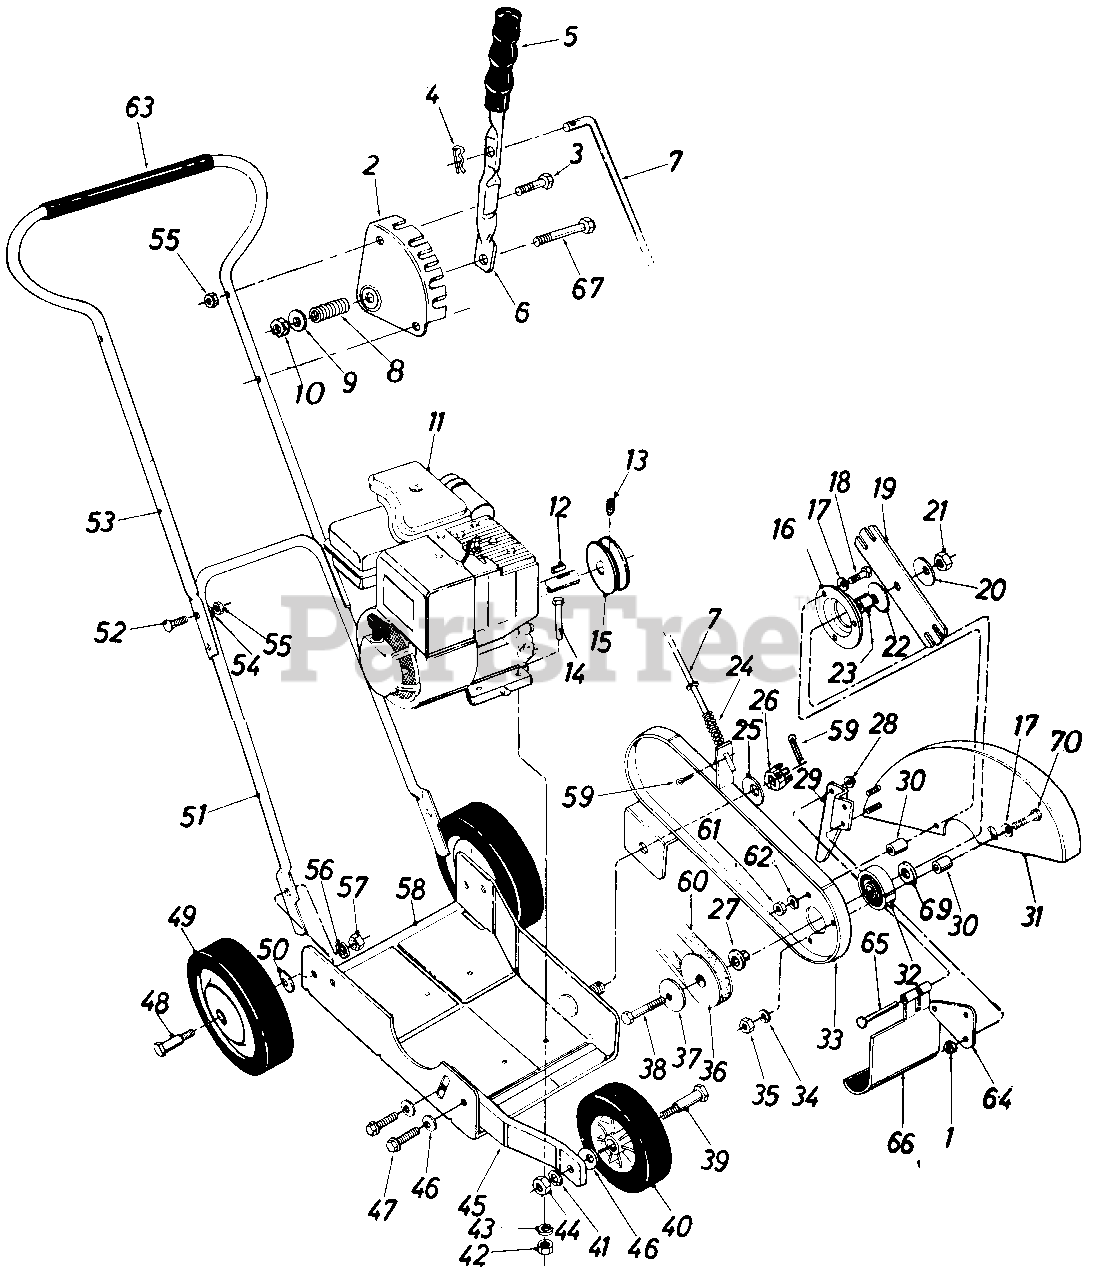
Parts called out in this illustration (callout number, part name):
1	Hex Cent. L.-Nut 1/4-20 Thd.
3	Hex Bolt 1/4-20 x 1.25" Lg.
4	Cotter Pin 1/8" Dia. x 1.0" Lg.
5	Grip
6	Clutch Handle
7	Clutch Rod
8	Compression Spring .50" O.D. x 1.38" Lg.
9	Fl.-Wash. .34" I.D. x .62" O.D x 063
10	Hex Cent. L.-Nut 5/16-18 Thd.
11	Engine
12	Sq. Key 3/16 x 1.0" Lg.*
13	Set Scr. 1/4-28 x 1/4" Lg.
14	Hex Bolt 5/16-18 x 1.50" Lg.*
15	Engine Pulley
16	Bearing Housing
17	Bell.-Wash. .34" I.D. x 88" O.D. x .060
18	Hex Bolt 5/16-18 x 1.25" Lg.*
20	Bell.-Wash. .535" I.D. x 1.50" O.D. x.052
21	Hex Cent. L.-Nut 1/2-20 Thd.
22	Bell.-Wash. .535" I.D. x 1.50" O.D. x .052
23	Spacer
24	Compression Spring .57" O.D. x 1.92" Lg.
25	Bell.-Wash. .535" I.D. x 1.50" O.D. x .052
26	Hex Castle Nut 1/2-20 Thd.
27	Shoulder Spacer
28	Push Cap
29	Guide
30	Spacer .354" I.D. x .635" O.D. x .510" Lg.
33	Spindle Bracket Ass'y.
34	L.-Wash. 5/16" I.D.*
35	Hex Nut 5/16-18 Thd.
36	1 Pulley Half
37	Bell.-Wash. .535" I.D. x 1.50" O.D. x.052
38	Hex Bolt 1/2-20 x 3.50" Lg.*
39	Shoulder Bolt .498" Dia. x 1.450
40	Wheel Ass'y. Comp. 6" Dia. x 1.50
41	L.-Wash. 3/8" I.D.
42	Hex Nut 5/16-18 Thd.
43	L.-Wash. 5/16" I.D.*
44	Hex Nut 3/8-16 Thd.*
45	Front Wheel Support
46	Bell.-Wash. .400" I.D. x 88" O.D. x.060
47	Hex Wash. Hd. Self Tap Scr. 3/8-16 x .75" Lg.
48	Shoulder Bolt .498" Dia. x 1.450
49	Wheel Ass'y. Comp. 7" Dia. x 1.50
50	Bell.-Wash. .400" I.D. x 88" O.D.
51	Lower Handle
52	Carriage Bolt 1 /4-20 x 1.25 " Lg. *
53	Upper Handle
54	L.-Wash. 1/4" I.D. *
55	Hex Nut 1/4-20 Thd. *
56	L.-Wash. 3/8" I.D.*
57	Hex Nut 3/8-16 Thd.
58	Base Ass'y.
59	Cotter Pin 1/8" Dia. x 1.0" Lg. *
60	3V-Belt 31.2" Lg.
61	Hex Nut 5/16-18 Thd.
62	L.-Wash. 5/16" I.D.*
63	Grip (Optional)
64	Flap Bracket
65	Hinge Pin
66	Debris Deflector
67	Hex Bolt 5/16-18 x 1.75" Lg. *
69	Fl.-Wash. .51 I.D. x 1.00 O.D. x.060
70	Hex Bolt 5/16-18 x 2.00" Lg. *
